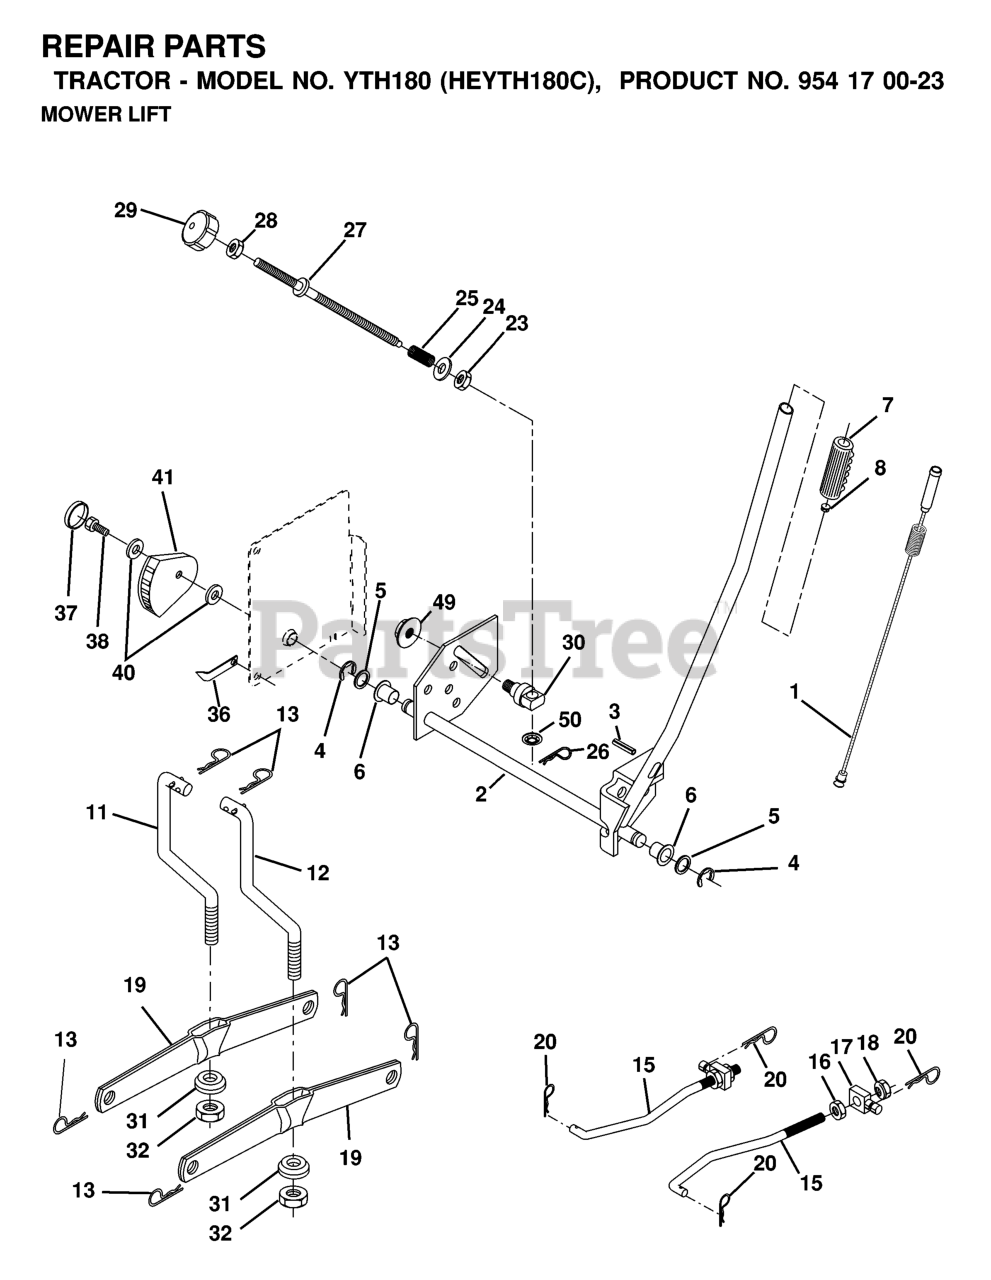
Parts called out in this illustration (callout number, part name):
1	WIRE ASM INNER W/ PLUNGER LT
2	SHAFT ASM R HANDLE
3	PIN GROOVE.
4	RETAINING RING LT
6	BEARING.NYLON
7	GRIP HANDLE
8	PLUNGER BUT KIT
11	LINK LIFT LH
12	LINK LIFT RH
13	RETAINER-SPRNG RB
15	LINK FRONT
16	NUT.HEX.JAM.1/2-13
17	TRUNION
18	NUT.LK.W/WSH.1/2.
19	ARM.REAR.SUSPENSION
20	SPRING RETAINER
25	SPRING**
26	RETAINER CLIP
27	ROD ADJ LIFT
28	NUT
29	KNOB INF 3/8-16
31	NUT CROWNLOCK 3/8-24
32	BEARING PIVOT
36	POINTER, HEIGHT INDICATOR(2 2)
38	SCREW 5/16-18X1
41	IND. HEIGHT STLT
49	NUT
50	NUT PUSH M
